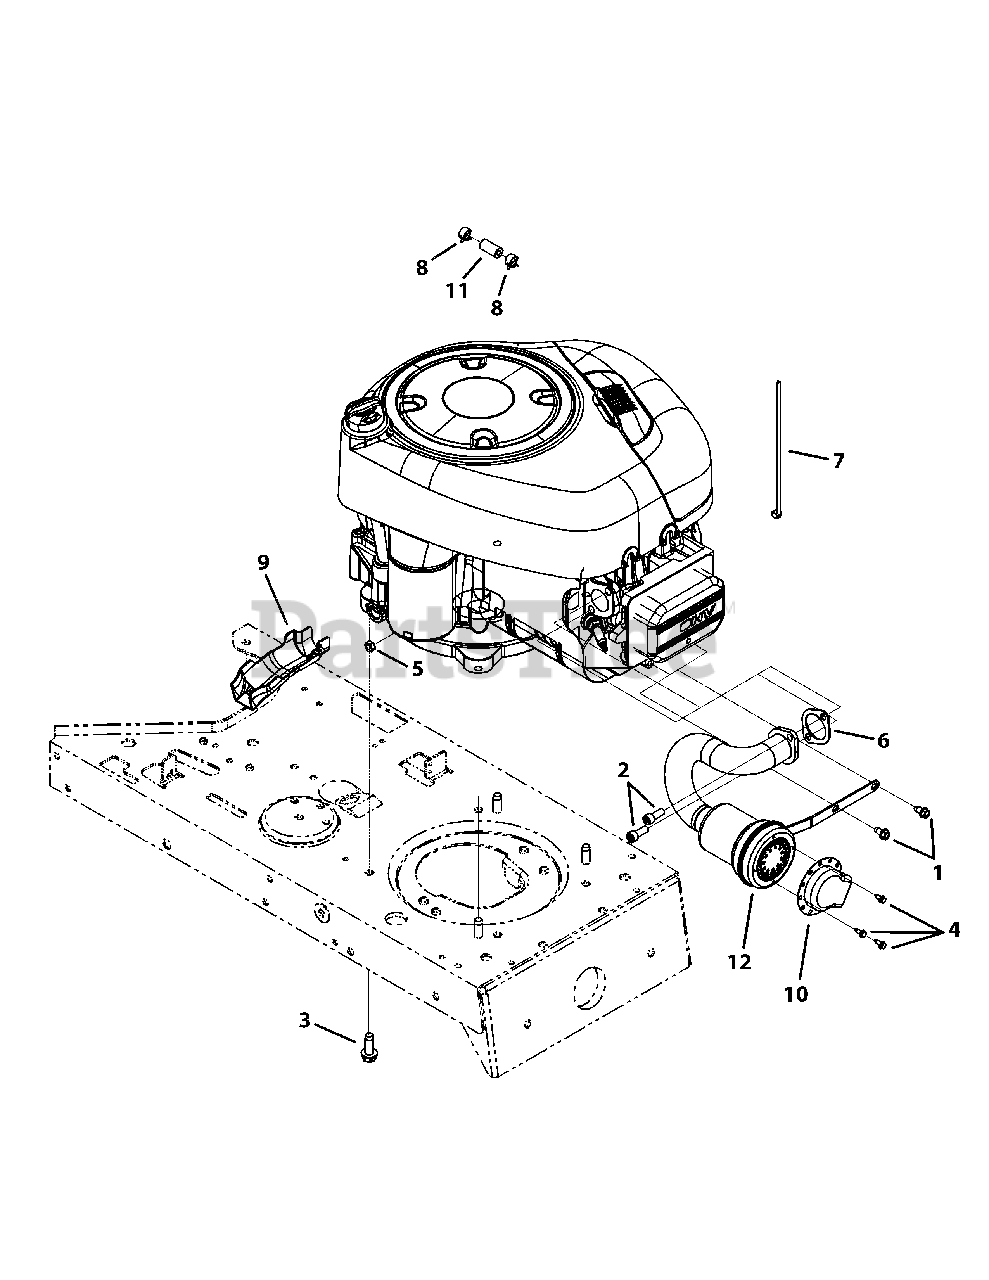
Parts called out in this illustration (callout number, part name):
1	Screw, 1/4-20 x .500
2	Socket Screw, 5/16-18 x .750
3	Screw, 3/8-16 x 1.000
4	Screw, 8-18 x .500
5	Sems Nut, 1/4-20
6	Exhaust Gasket
7	Cable Tie
8	Hose Clamp, .490 Diameter
9	Oil Drain Sleeve
10	Muffler Deflector
11	Fuel Hose, Low Permeation
12	Muffler
